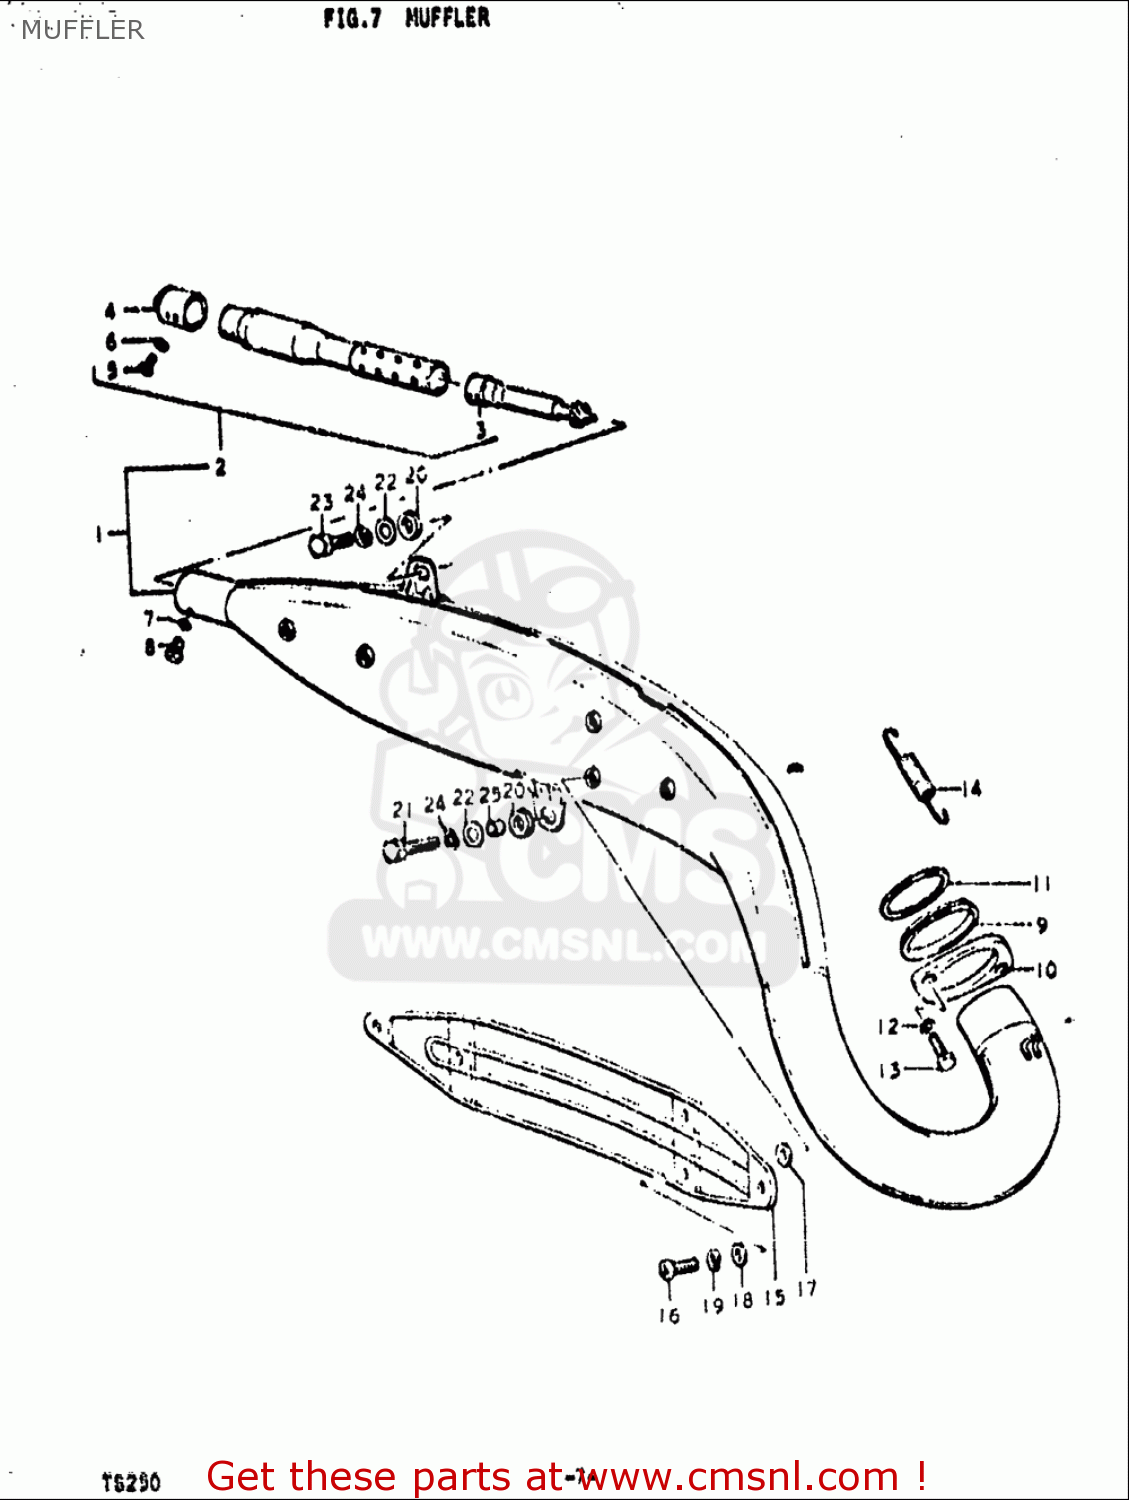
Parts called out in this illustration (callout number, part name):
3	TUBE,MUFFLER CLEAN OUT
4	CUTTER,SPARK ARRESTER
5	SCREW
6	WASHER,LOCK
7	GASKET(6.2X12X1.5) (NAS)
8	SCREW
9	GASKET,EXHAUST PIPE (NAS)
10	CLAMP,EXHAUST PIPE
11	WASHER,EXHAUST PIPE
12	WASHER,LOCK
13	BOLT
14	SPRING
16	SCREW
17	GASKET(6.2X12X1.5) (NAS)
18	WASHER
19	WASHER,LOCK
21	BOLT
22	WASHER
23	BOLT
24	WASHER,LOCK
25	SPACER(8.2X12X17)
